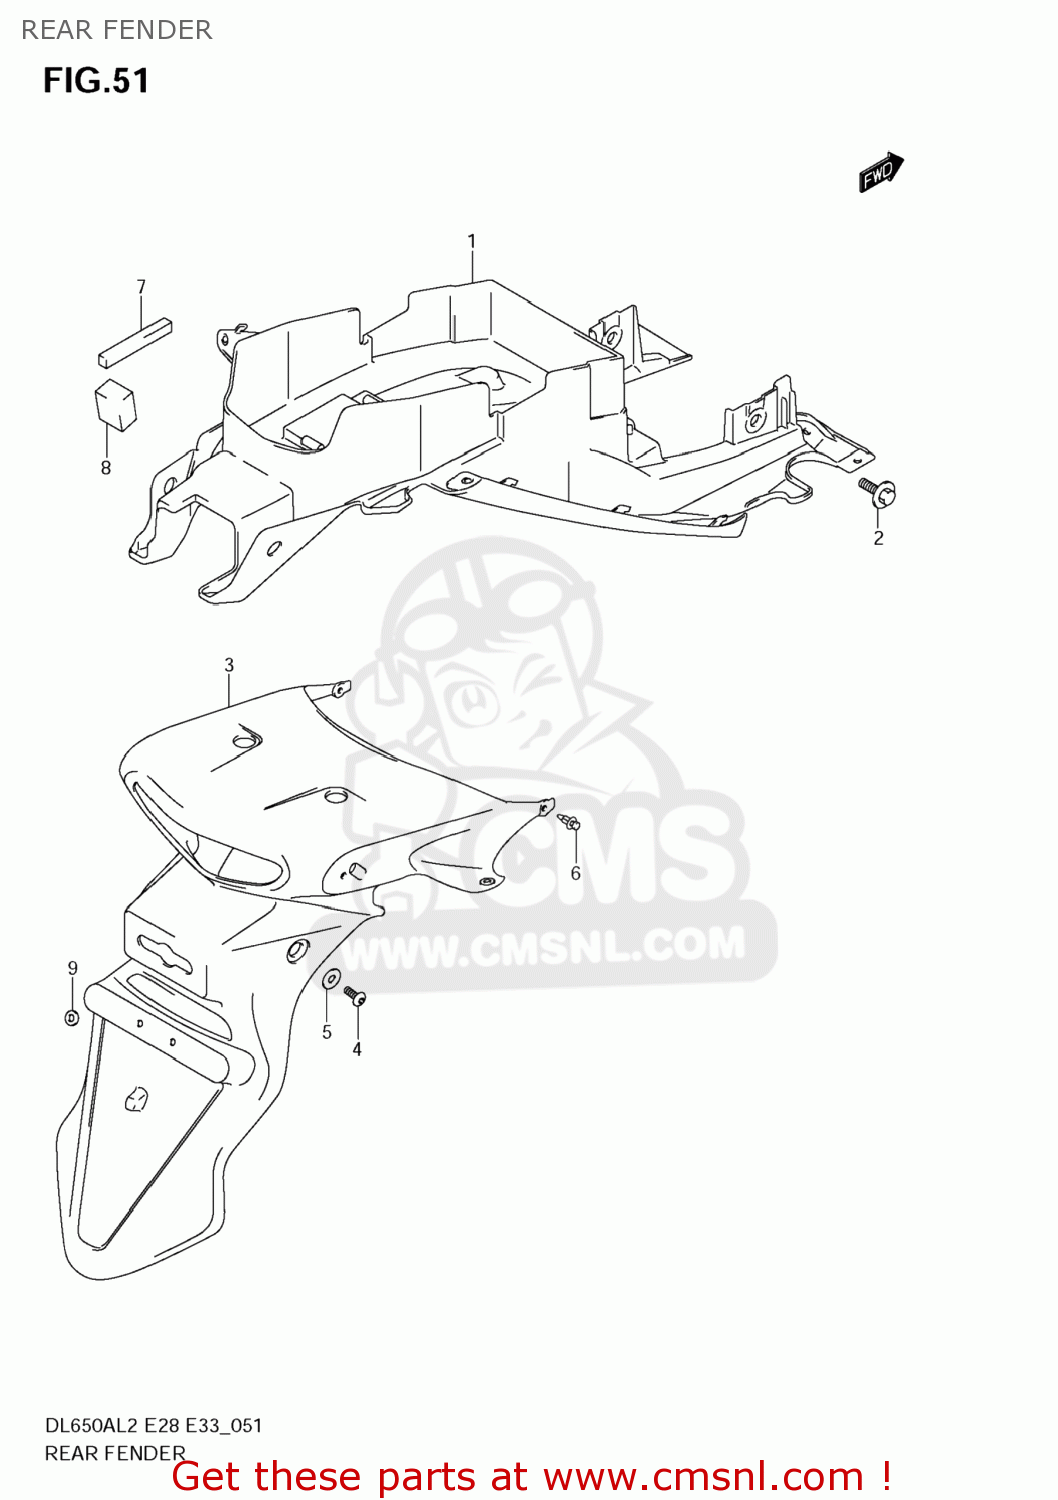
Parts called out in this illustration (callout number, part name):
1	FENDER,RR FR
2	BOLT(6X13)
3	FENDER,RR RR
4	SCREW(6X16)
5	WASHER(6.5X18X1.6)
6	CLIP(BLACK)
7	CUSHION,SEAT TAIL COVER CTR
8	CUSHION,RR FENDER RR
9	WASHER
